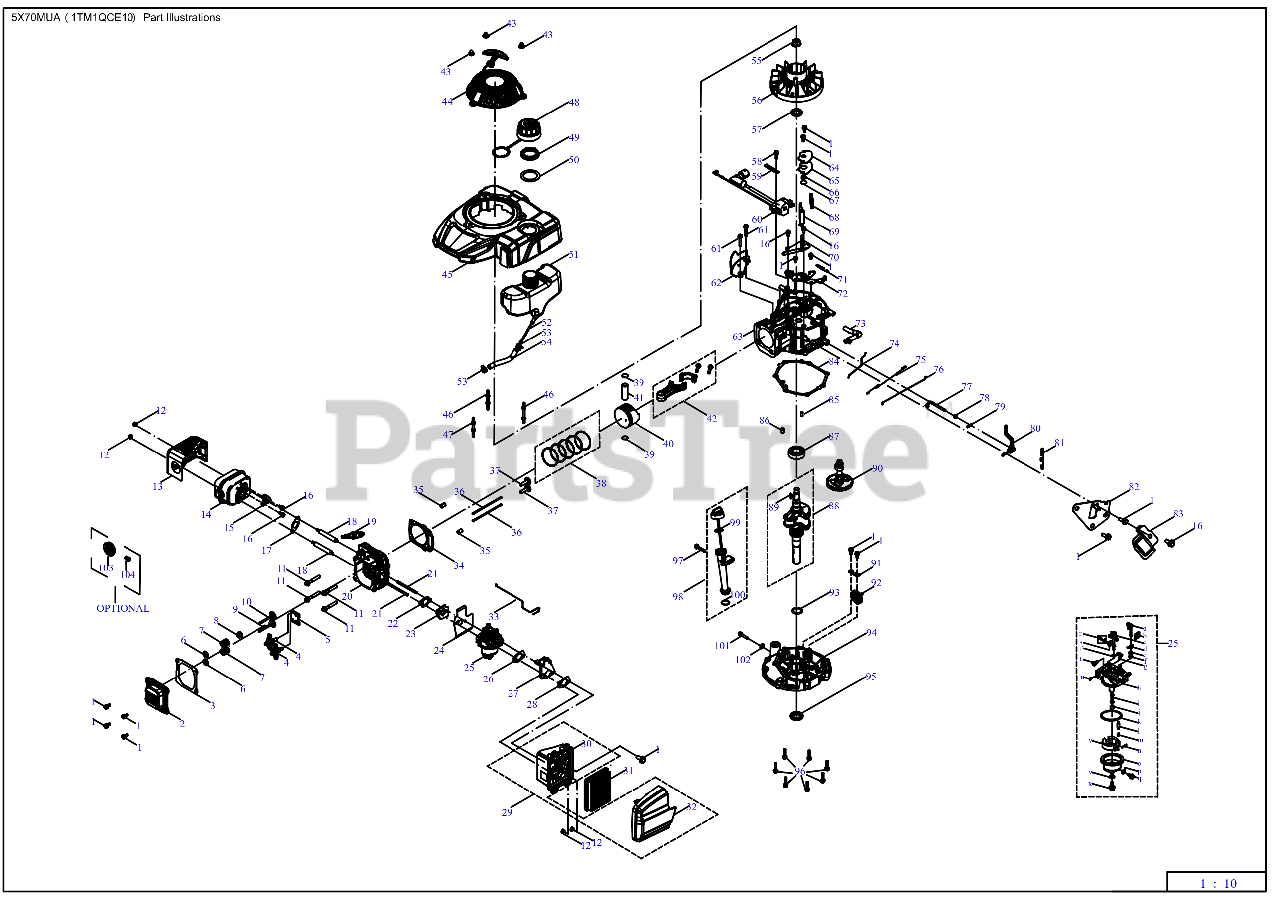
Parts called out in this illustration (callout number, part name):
1	BOLT M6-1 x 14 GR8.8
2	VALVE COVER
3	VALVE COVER GASKET
4	ROCKER ARM ASSEMBLY
5	PUSH ROD GUIDE
6	INTAKE VALVE SPRING RETAINER
7	VALVE SPRING
8	INTAKE VALVE SEAL
9	EXHAUST VALVE
10	INTAKE VALVE
11	SCREW M8 x 54 GR10
12	HEX NUT
13	MUFFLER SHIELD
14	MUFFLER ASSEMBLY
15	THERMOSTAT
16	BOLT M6-1 x 12 GR8.8
17	MUFFLER GASKET
18	STUD M6-1 x 95
19	SPARK PLUG
20	CYLINDER HEAD
21	CARBURETOR STUD-M6 x 87
22	CARBURETOR INSULATOR GASKET
23	CARBURETOR INSULATOR
24	CARBURETOR GASKET
25	CARBURETOR ASSEMBLY HY-5X70A
26	CHOKE TEMP CONTROL BRACKET GSKT
27	AIR FILTER BRACKET
28	AIR FILTER BASE GASKET
29	AIR FILTER ASSEMBLY
30	AIR FILTER HOUSING BASE
31	AIR FILTER
32	AIR FILTER COVER
33	TEMPERATURE CONTROL LINKAGE
34	CYLINDER HEAD GASKET
35	DOWEL PIN
36	PUSH ROD
37	TAPPET
38	PISTON RING 4PC SET
39	PISTON PIN SNAP RING
40	PISTON ASSEMBLY
41	PISTON PIN
42	CONNECTING ROD ASSEMBLY
43	ACORN NUT
44	RECOIL STARTER ASSEMBLY
45	ENGINE SHROUD W/O IGNITION SWITCH
46	STARTER/SHROUD REAR STUD
47	STARTER/SHROUD FRONT STUD
48	FUEL CAP W/TETHER
49	FUEL TANK NUT
50	FUEL TANK UPPER GROMMET
51	FUEL TANK
52	FUEL FILTER
53	HOSE CLAMP
54	FUEL HOSE
55	FLYWHEEL NUT
56	FLYWHEEL
57	CRANKSHAFT SEAL
58	BOLT M6-1 x 20 GR8.8
59	FLEXIBLE CLAMP
60	IGNITION COIL ASSEMBLY
61	BOLT M6-1 x 25 GR8.8
62	ENGINE BRAKE COVER PLATE
64	BREATHER COVER PLATE
65	BREATHER GASKET
66	BREATHER VALVE SPRING
67	BREATHER VALVE
68	BREATHER SCREEN
69	AIR VANE
70	AIR VANE BRACKET
71	ENGINE BRAKE SPRING
72	ENGINE BRAKE ASSEMBLY
73	BREATHER HOSE ASSEMBLY
74	CHOKE LINKAGE
75	THROTTLE LINKAGE
76	THROTTLE SPRING
77	GOVERNOR ARM SHAFT
78	GOVERNOR SEAL
79	COTTER PIN
80	GOVERNOR ARM ASSEMBLY
81	GOVERNOR SPRING
82	COMPONENT BRACKET
83	GOVERNOR SHIELD
84	CRANKCASE COVER GASKET
85	DOWEL PIN
86	DOWEL PIN
87	BEARING
88	CRANKSHAFT ASSEMBLY
89	FLYWHEEL KEY
90	CAMSHAFT ASSEMBLY
91	GOVERNOR GEAR MOUNTING PLATE
92	GOVERNOR GEAR/SHAFT ASSEMBLY
93	THRUST WASHER
94	CRANKCASE COVER
95	LOWER CRANKSHAFT OIL SEAL
96	BOLT-M6-1 x 28 GR8.8
97	BOLT M6-1 x 35 GR8.8
98	OIL DIPSTICK ASSEMBLY
99	O-RING
100	O-RING
101	OIL DRAIN PLUG
102	WASHER
103	SPARK ARRESTOR
104	SCREW M3.5 x 9.5
